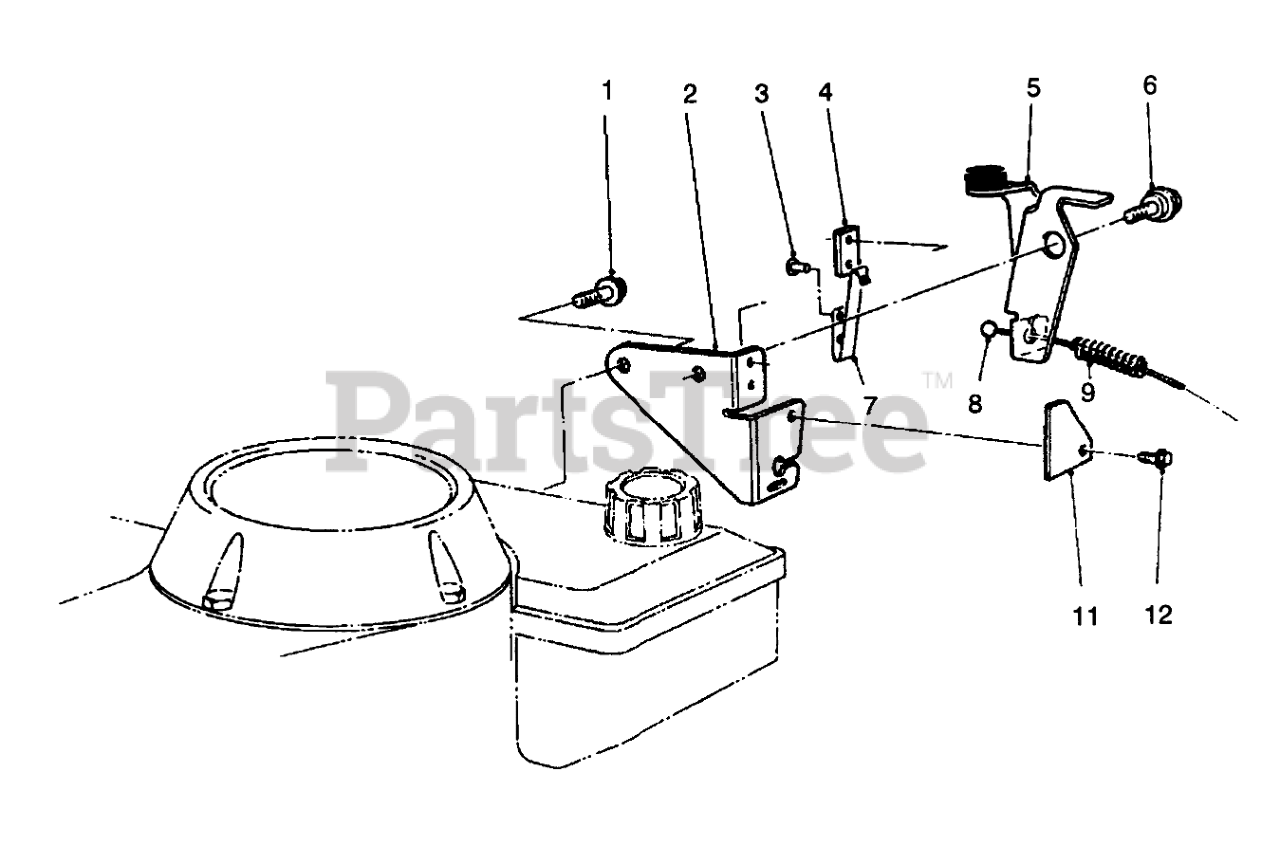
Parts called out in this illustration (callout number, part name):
1	THO FORM SCREW M6 X 1
2	Plate-Mounting Assembly (Incl. Ref. #3, 4 & 7)
3	RIVET-PLASTIC
4	STRAP-INSULATING
5	BRAKE PLATE ASM
6	Screw-Shoulder
7	STRAP-GROUND
8	BRAKE CABLE
9	SPRING-COMPRESSION
11	STOP-GROUND STRAP
12	SCREW-HWH
